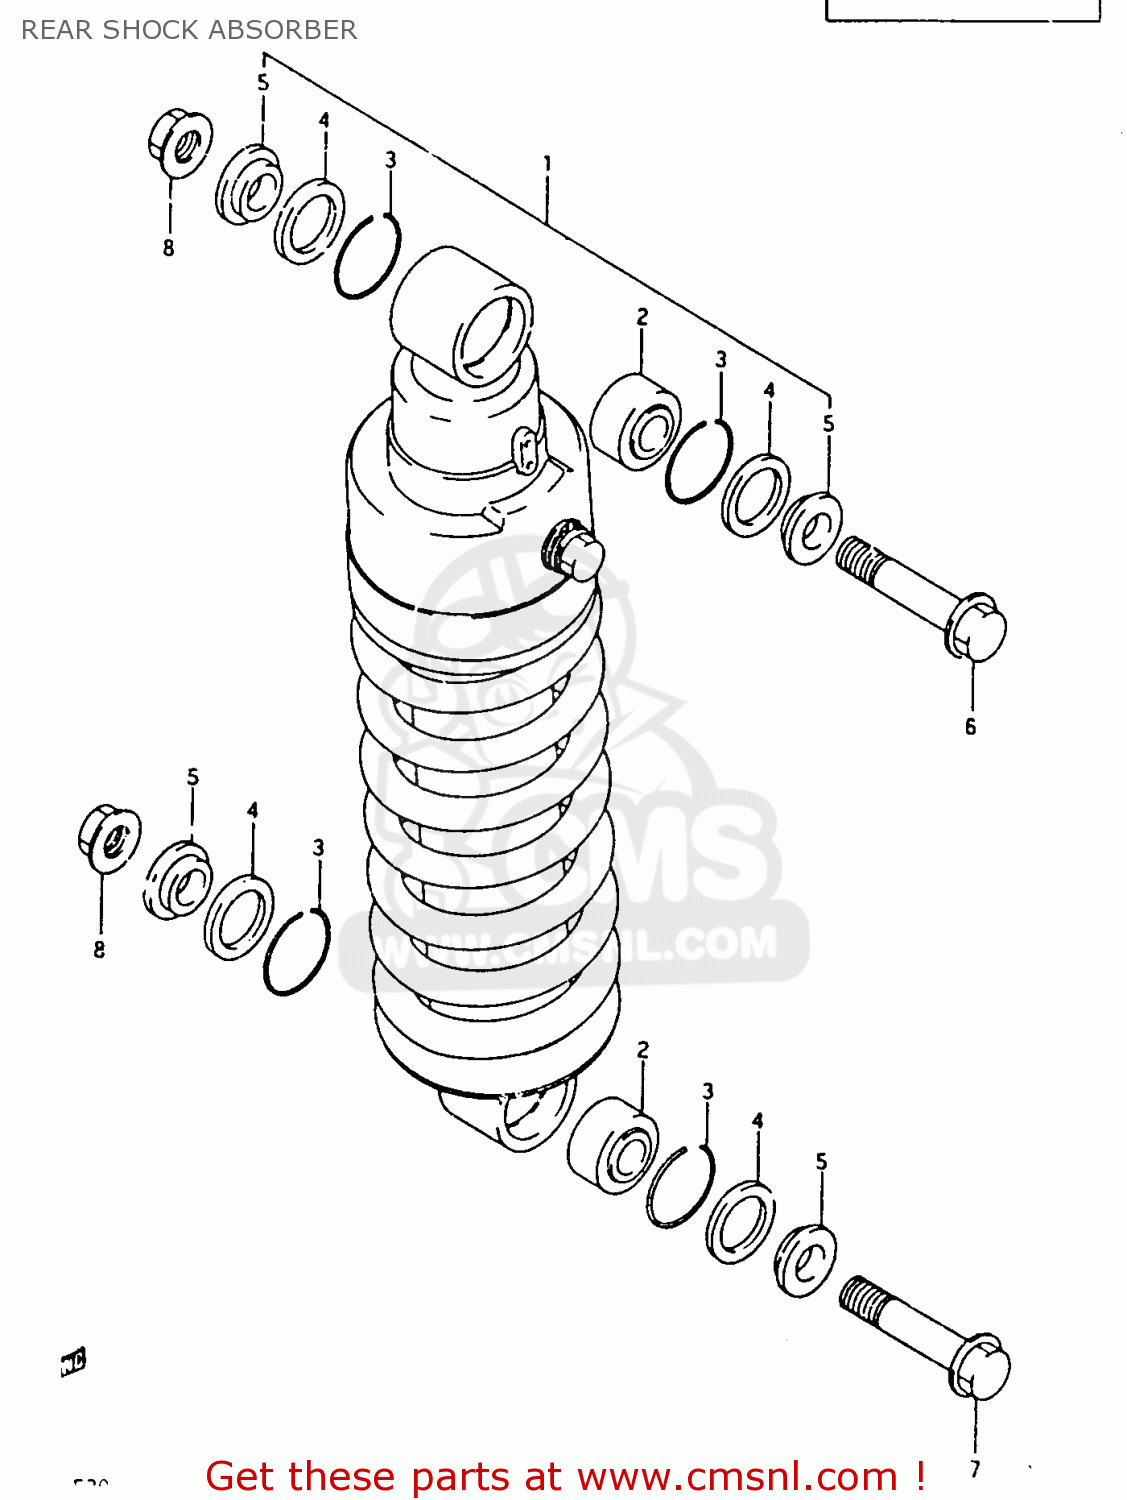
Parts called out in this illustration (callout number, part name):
1	ABSORBER ASSY, REAR SHOCK (BLUE)
2	BEARING,REAR SHOCK ABSORBER
3	RING
4	SEAL,DUST RR SHOCK ABSORBER
5	COLLAR
6	BOLT(10X54)
7	BOLT(10X52)
8	NUT
